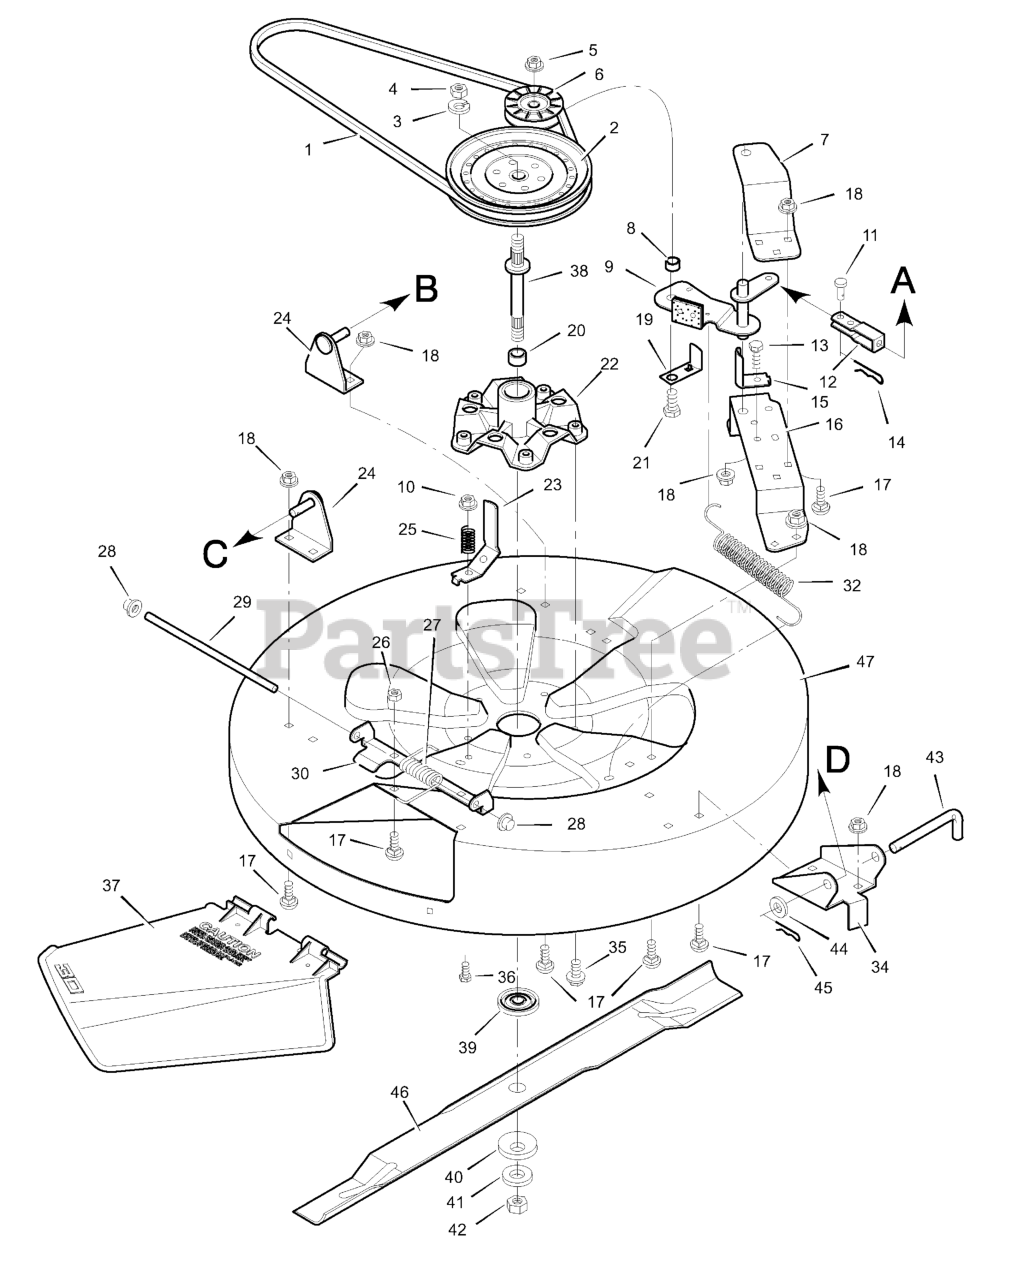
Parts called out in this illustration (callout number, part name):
1	Belt, Mower Drive
2	Pulley, Splined
3	Lockwasher
4	Locknut, Hex
5	Nut, Hex
6	Pulley, Idler
7	Bracket, Upper Idler
9	Assembly, Blade Idler
10	Locknut, Flange
11	Pin, Clevis
13	Bolt, Hex
14	Pin, Hair
15	Guide, Belt
16	Bracket, Lower Idler
17	Bolt, Carriage
18	Nut, Flange
19	Guide, Belt
21	Bolt, Hex
22	Housing, Mandrel
23	Guide, Belt
24	Bracket, Hanger
25	Spring, Compression
26	Nut, Hex
27	Spring - Torsional
28	Push On Cap
30	Hinge, Chute Deflector
32	Spring, Extension
34	Bracket, Front
36	Bolt, Hex
37	Deflector, Chute
38	Mandrel
39	Adapter, Blade
40	Washer, Belleville
41	Washer, Hardened
42	Nut, Hex
43	Pin, Pull
45	Pin, Hair
46	Blade, Standard
